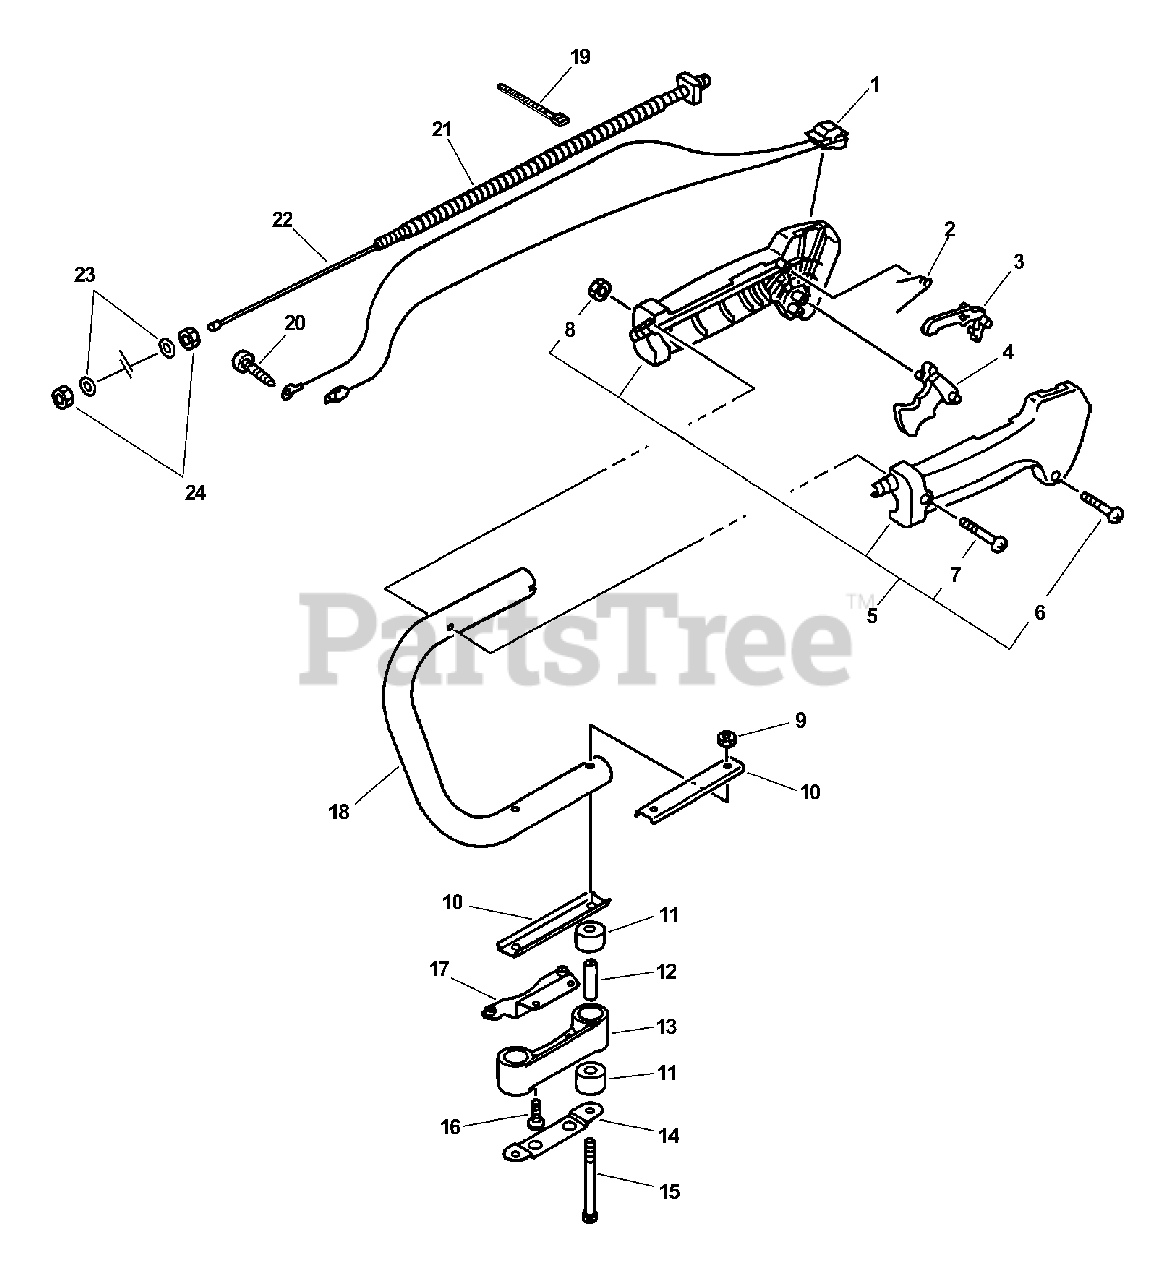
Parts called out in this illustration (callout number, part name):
1	IGNITION SWITCH ASSY
2	SPRING, TORSION
3	LOCKOUT, THROTTLE
4	TRIGGER, THROTTLE
5	CONTROL HANDLE KIT
6	SCREW 3×25
7	SCREW 5×30
8	NUT M5
9	NUT, LOCK M5
12	SPACER
13	BRACKET, HANDLE
15	BOLT 5×60
16	SCREW 5×16
18	HANDLE, REAR
19	TIE, CABLE
20	SCREW 5×10
22	CABLE, THROTTLE
23	WASHER 6.5×11.5×0.8
